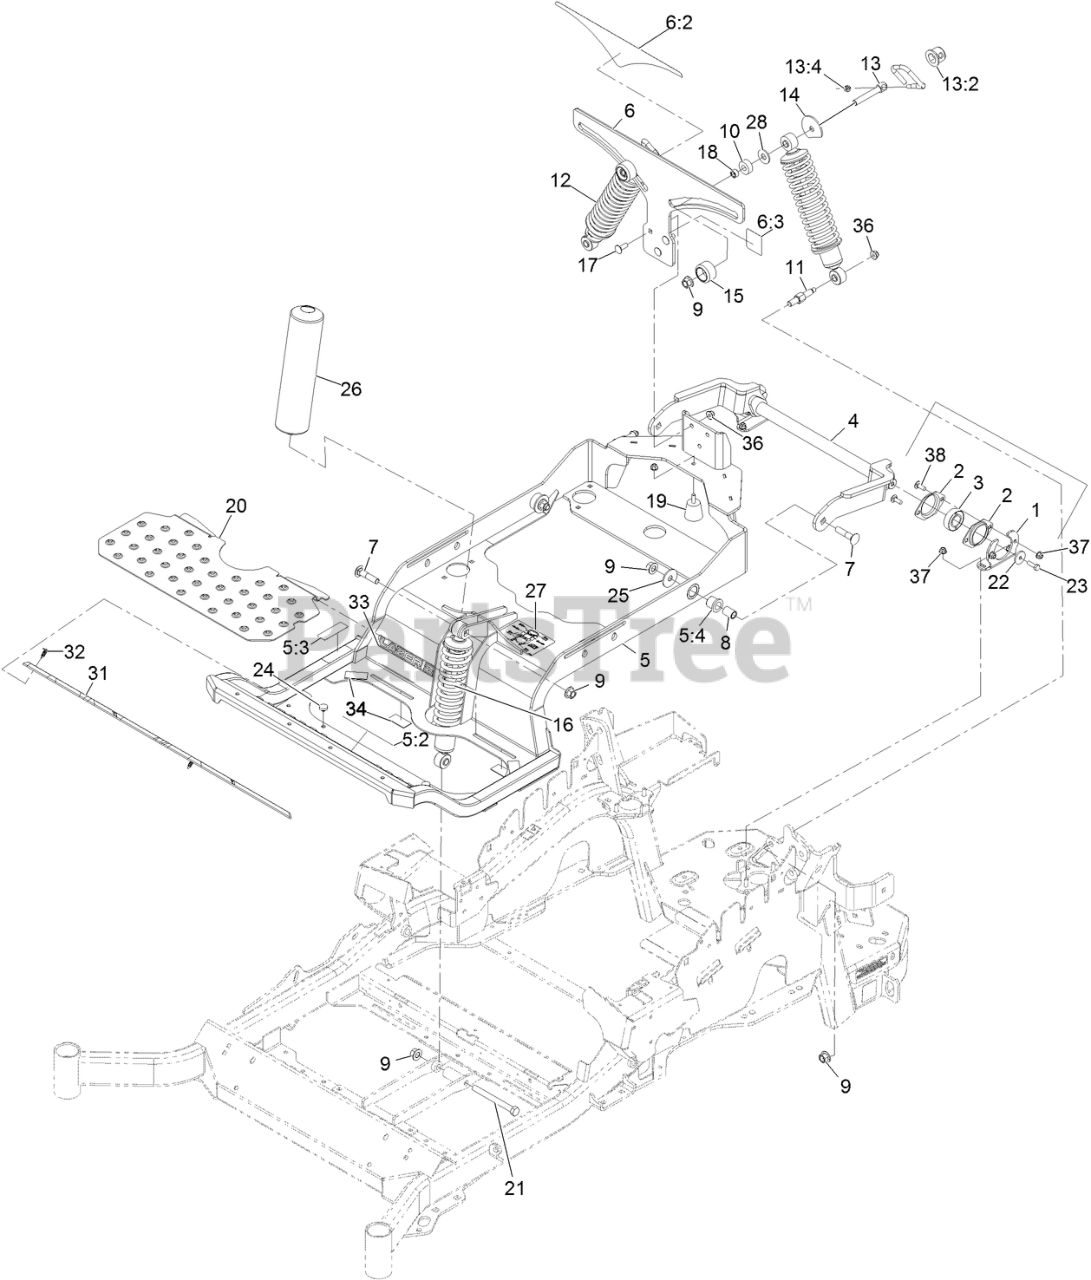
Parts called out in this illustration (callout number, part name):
1	BRACKET-BEARING
2	HOUSING-BEARING, FLANGE
3	BEARING
4	ARM-TRAILING
5	SUBFRAME ASM
5:2	DECAL-DANGER
5:3	DECAL-BRAKE, PARKING
5:4	BUSHING-FLANGE
6	BRACKET-MOUNTING
6:2	DECAL-ADJUSTMENT, RIDE
6:3	DECAL-LOCK, CAM
7	SCREW-CARR
8	SPACER-ALUMINUM
9	Nut-Lock 1/2-13
11	BOLT-SHOULDER
12	SHOCK/SPRING ASM
13	CAM LOCK ASM
13:2	CAP-LOCK
13:4	NUT-HEX
14	PLATE-STOP
15	KNOB-FRONT
16	SHOCK ASM-FRONT
16	SHOCK/SPRING ASM
17	SCREW-CARR
18	BEARING-NEEDLE
19	BUMPER-RUBBER
20	FLOORPAN
21	SCREW-HH
22	WASHER-FLAT
23	SCREW-HH, THREAD LOCKING
25	WASHER-THRUST
26	COVER-SHOCK
27	DECAL-SERVICE AID
28	WASHER-FLAT
31	FLOOR MAT
32	PLUG-PLASTIC
33	DECAL-LAZER LOGO
34	PAD-RUBBER
36	NUT-HF, NI
37	NUT-HF, NI
38	BOLT-CARR
